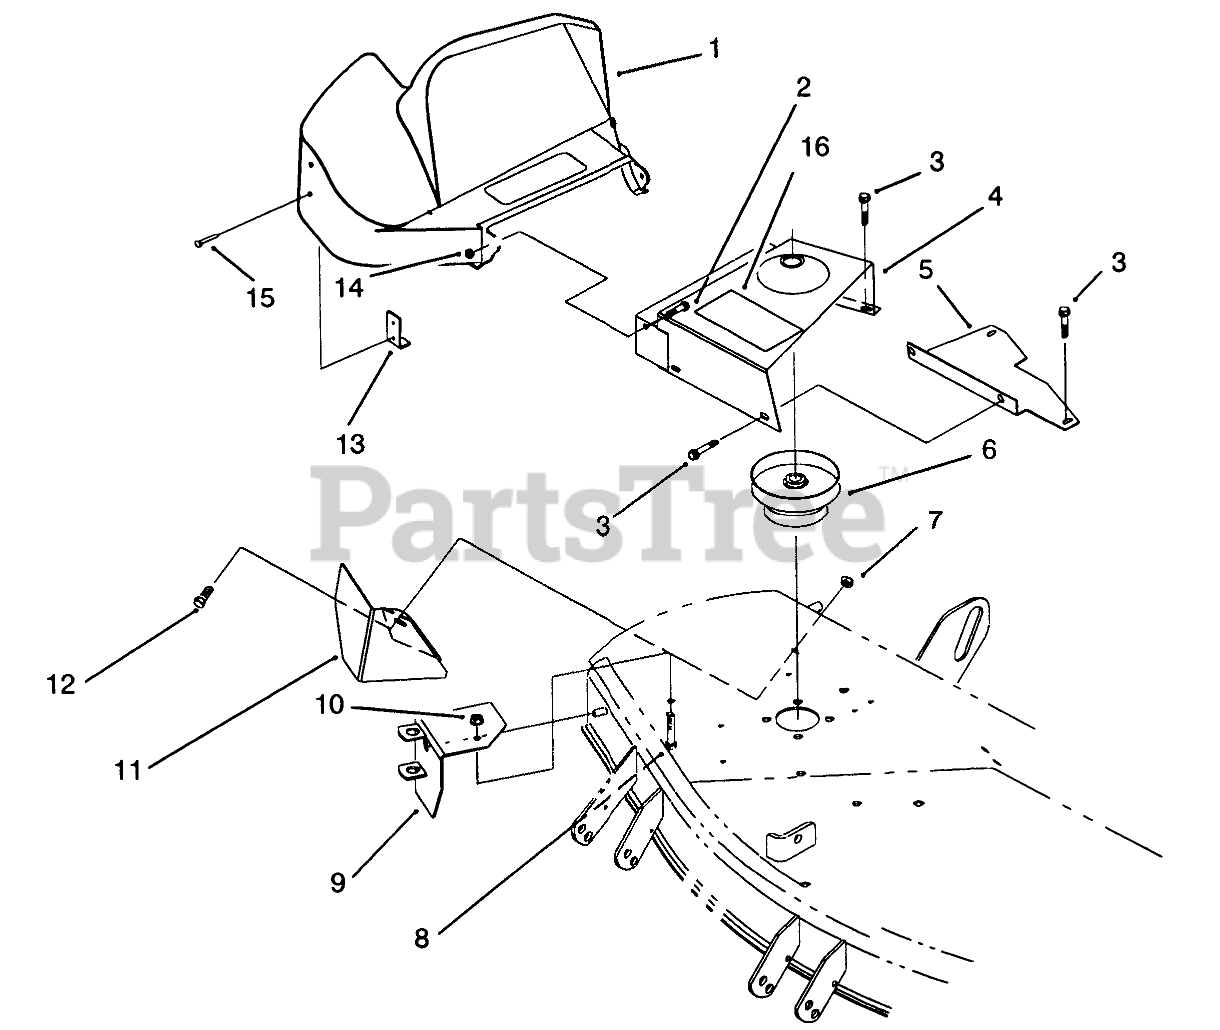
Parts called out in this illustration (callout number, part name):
1	SHIELD-BELT
2	SCREW-HH
3	Bolt
4	42" Inner Shield Assembly (Incl. Ref. #16)
5	42" ADAPTOR SHIELD B
6	PULLEY
7	NUT-LOCK, NI
8	SCREW-HH
9	PIVOT SUPPORT ASM
10	NUT-HF
11	42" DEFLECTOR B
12	SCREW-CARR
13	BRACKET-SUPPORT, SHIELD
14	NUT-LOCK, NI
15	RIVET-POP
16	DECAL-DANGER, THROWN OBJECT
